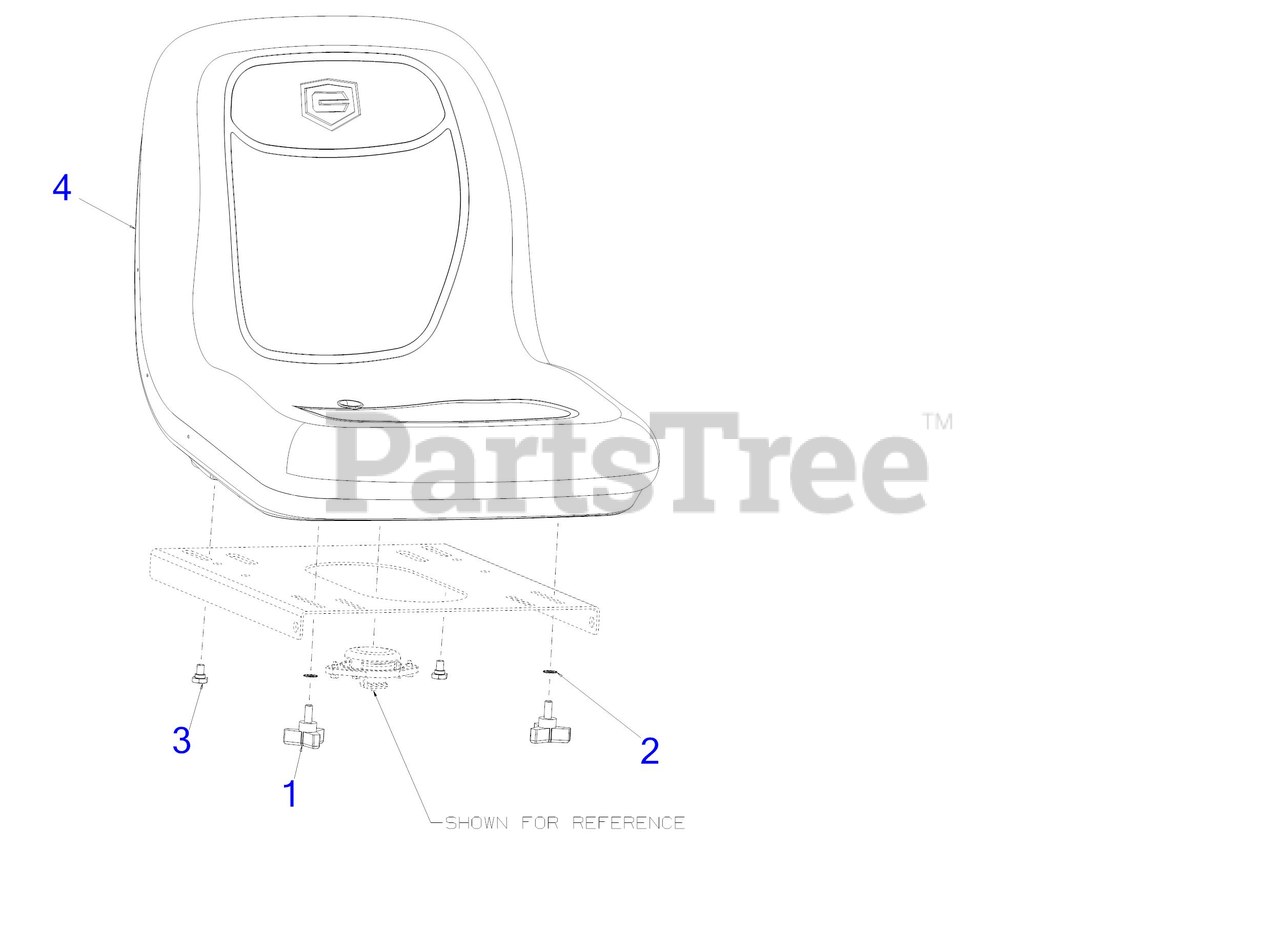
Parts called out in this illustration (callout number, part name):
1	THREE ARM KNOB
2	WASHER
3	SHOULDER SCREW .437
4	SEAT-19" 4 PT MTG
